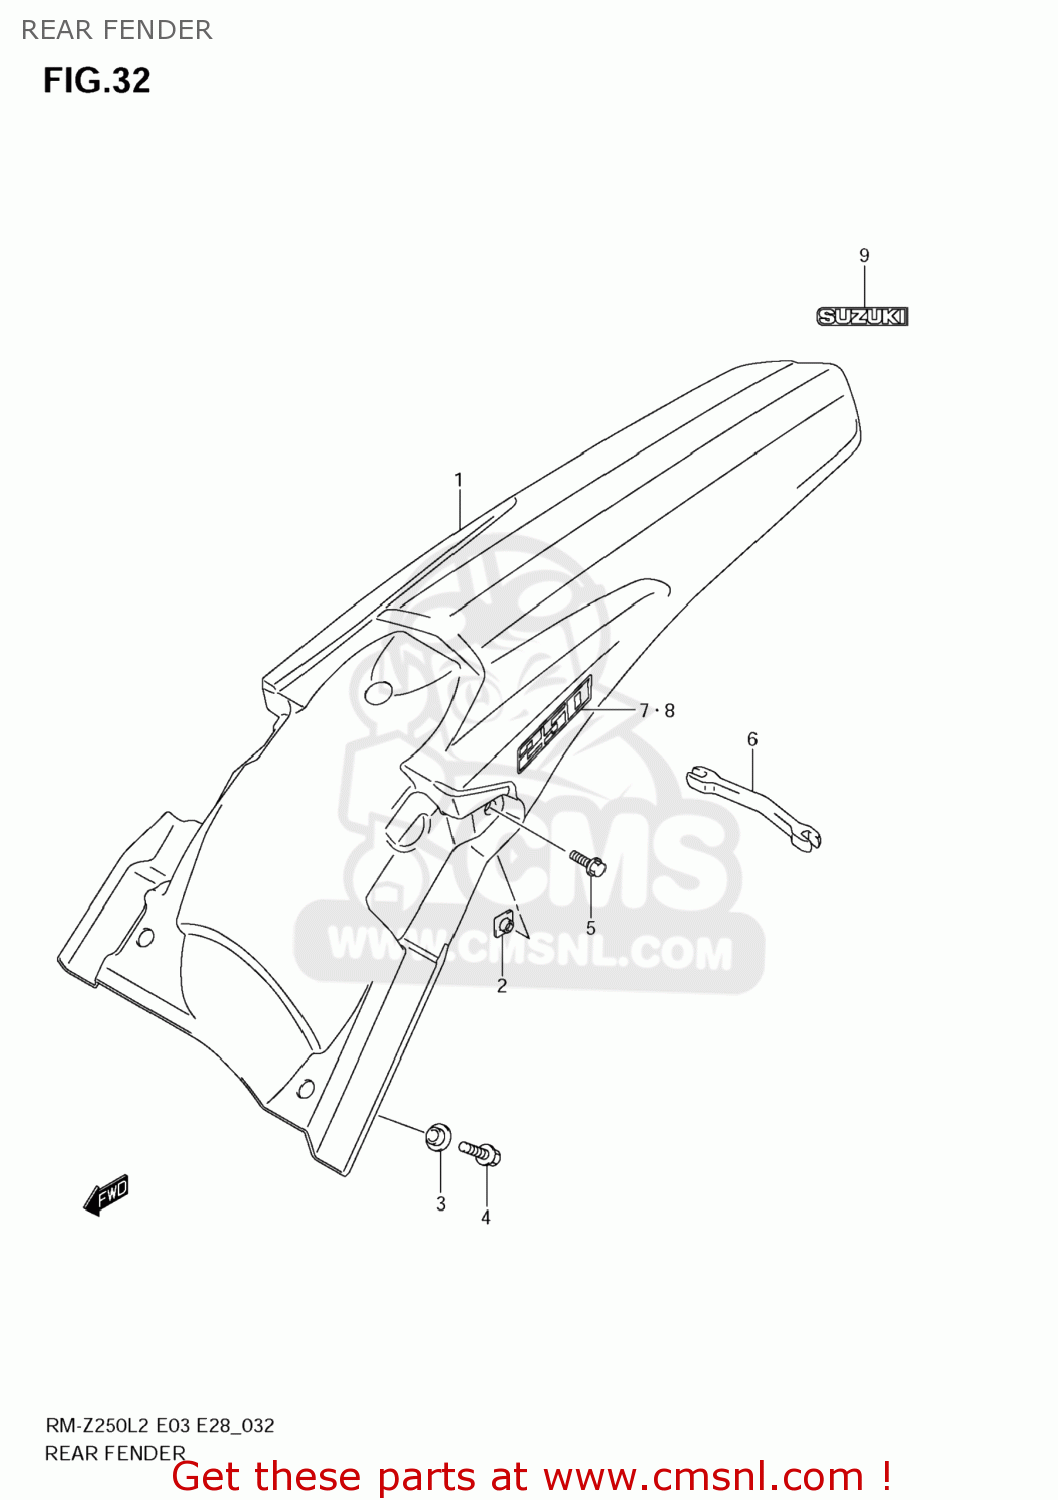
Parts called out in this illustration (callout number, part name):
1	FENDER,RR
2	NUT,RR REFLECTOR
3	WASHER,FR FENDER
4	BOLT
5	BOLT
6	OPEN SPANNER(6.4X6.8)
7	EMBLEM,RR FENDER,R
8	EMBLEM,RR FENDER,L
9	EMBLEM,SUZUKI
